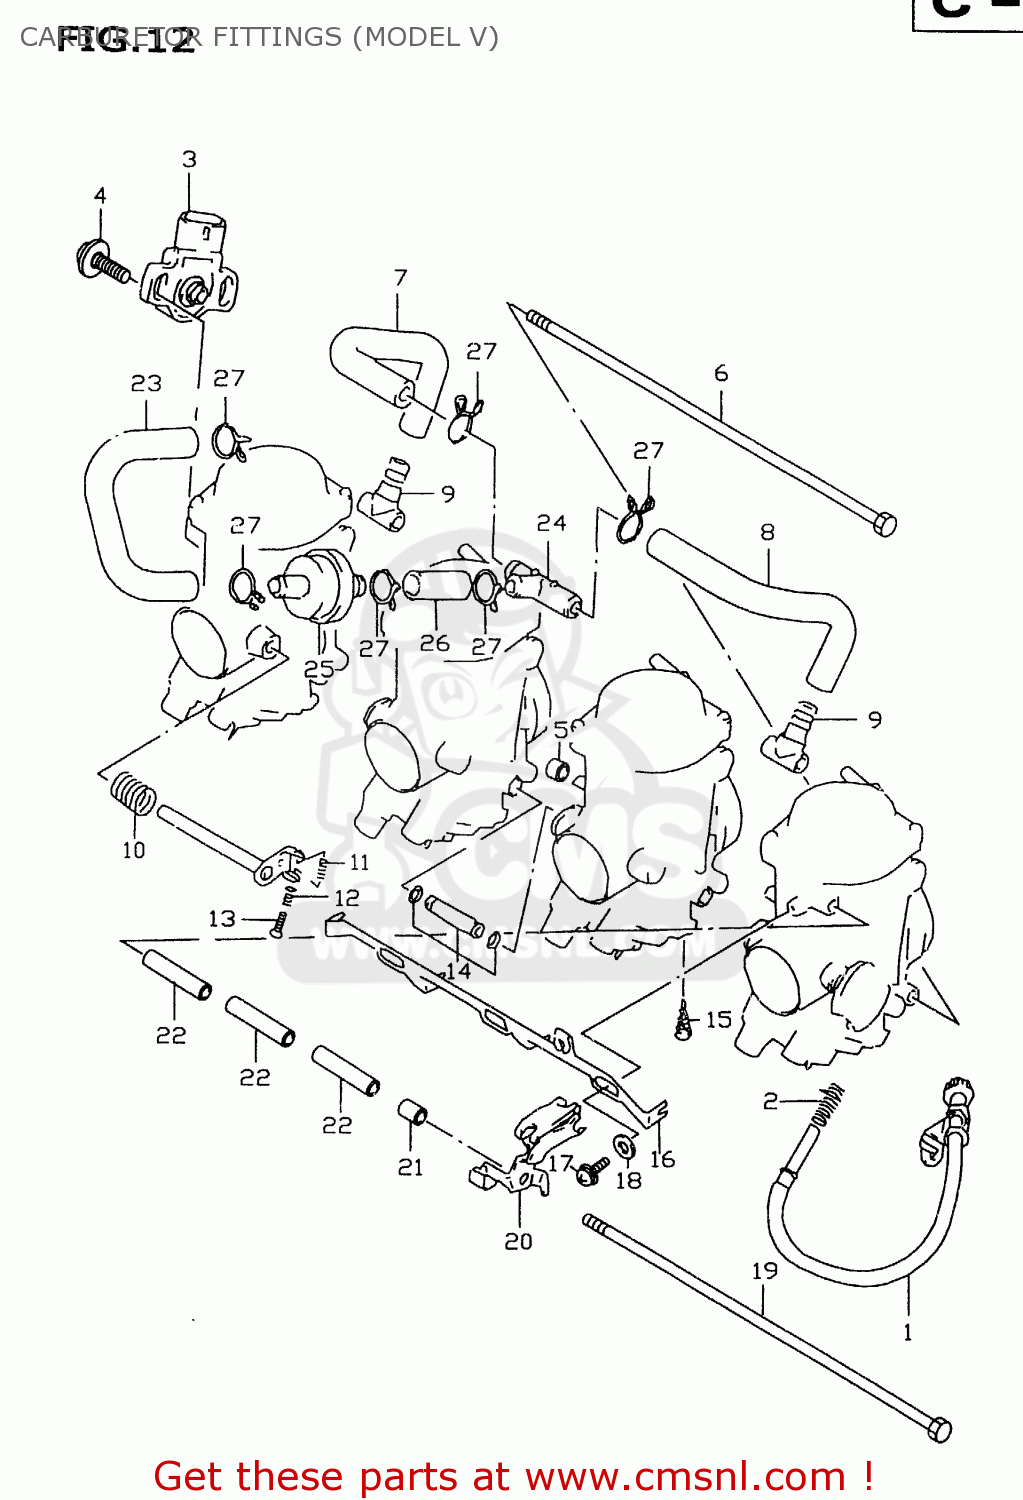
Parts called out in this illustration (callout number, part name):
1	ADJUSTER
2	SPRING
3	SENSOR ASSY,THROTTLE
4	SCREW, SENSOR
5	PIPE
6	BOLT
7	HOSE
8	HOSE
9	3 WAY
10	SPRING
11	SPRING,THROTTLE SCREW
12	SPRING
13	SCREW
14	NIPPLE,CARBURETOR
15	FILTER
16	LEVER,STARTER
17	SCREW
18	PACKING
19	BOLT
20	BRACKET
21	PIPE
22	PIPE
23	HOSE,AIR VENT(NO.1)
24	JOINT
25	FILTER,AIR VENT
26	HOSE(11X15X600)
27	CLIP
